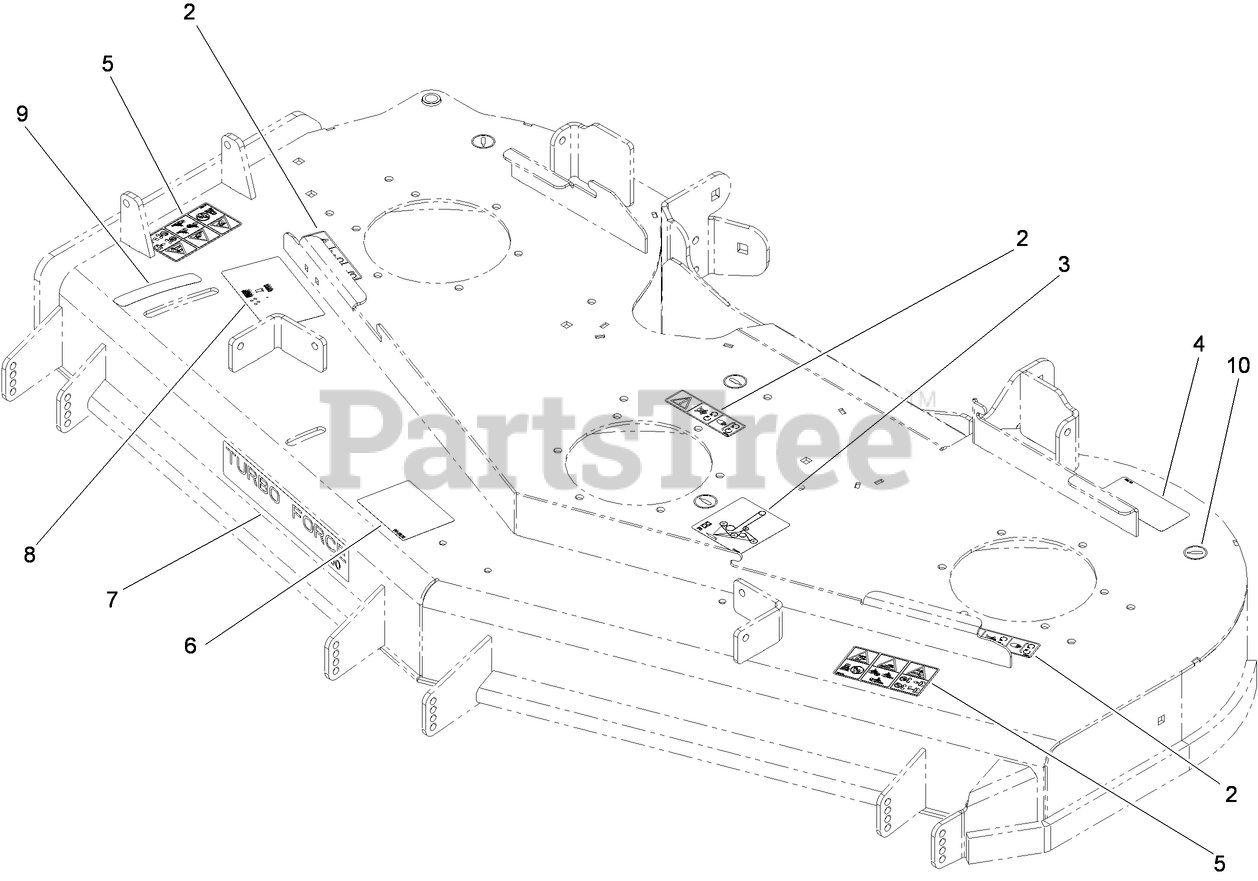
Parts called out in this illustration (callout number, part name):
2	DECAL-MISSING, COVER
3	DECAL-ROUTING, DECK BELT
4	DECAL-TORQUE, BLADE BOLT
5	DECAL-DANGER
6	DECAL-ANTI SCALP
8	DECAL-ADJUSTMENT, BAFFLE
9	DECAL-SETTING, BAFFLE
10	DECAL-GREASE
